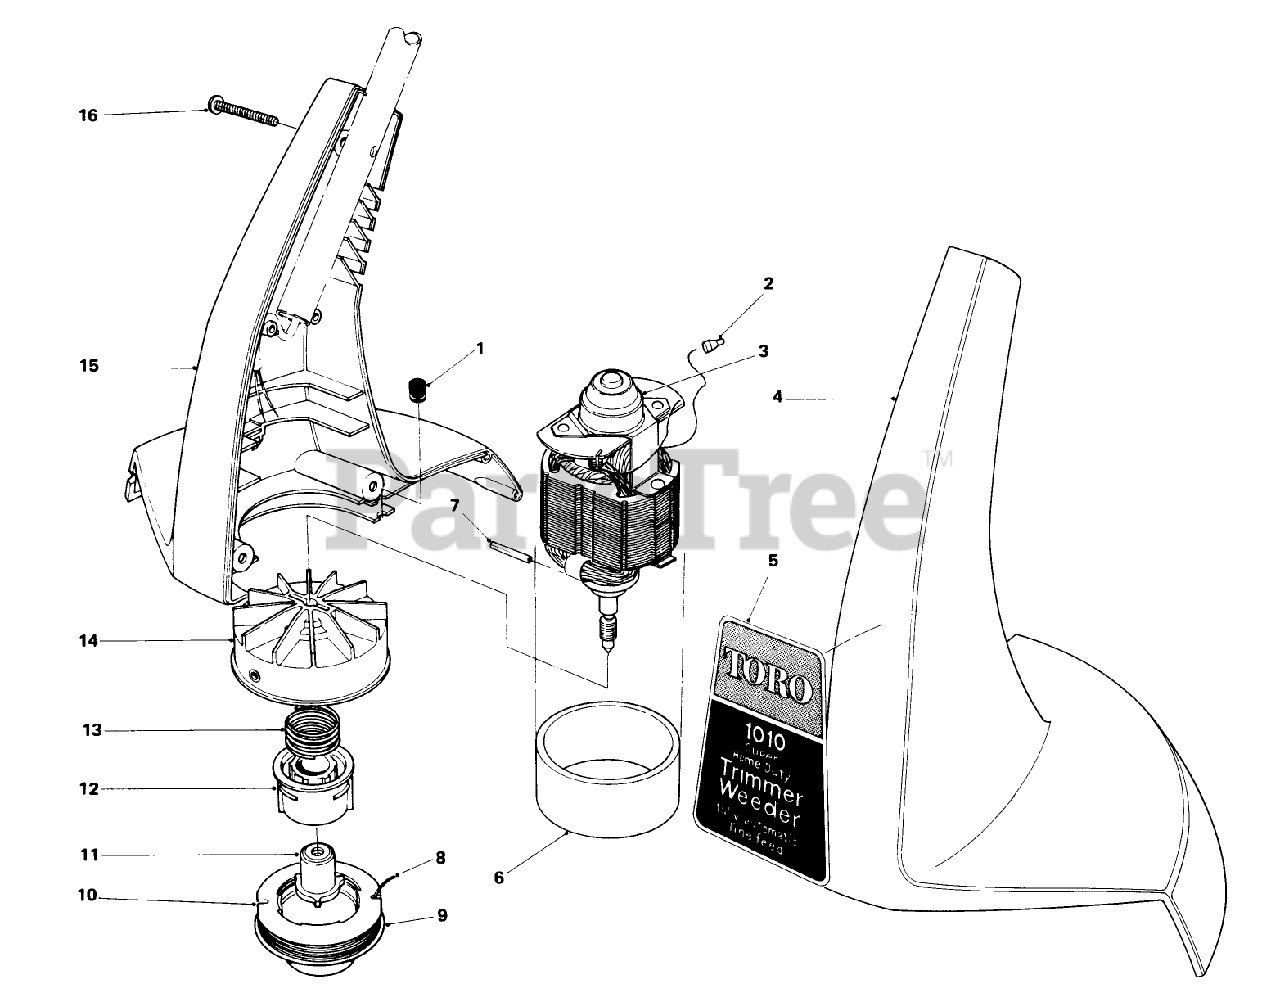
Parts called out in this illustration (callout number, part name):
1	GROMMET
2	Electrical Connector
3	Motor
4	Housing-L.H.
5	Decal-Housing
6	DAMPENING SLEEVE
7	COIL PIN
8	Filament Line 30-(.050 Dia.)
9	SPOOL CAP
10	Prewound Spool Cap
11	DRIVER DETENT
12	CORE - SPOOL
13	SPRING-COMPRESSION
14	FAN HUB ASM
15	Housing Assembly, R.H.
16	Screw
